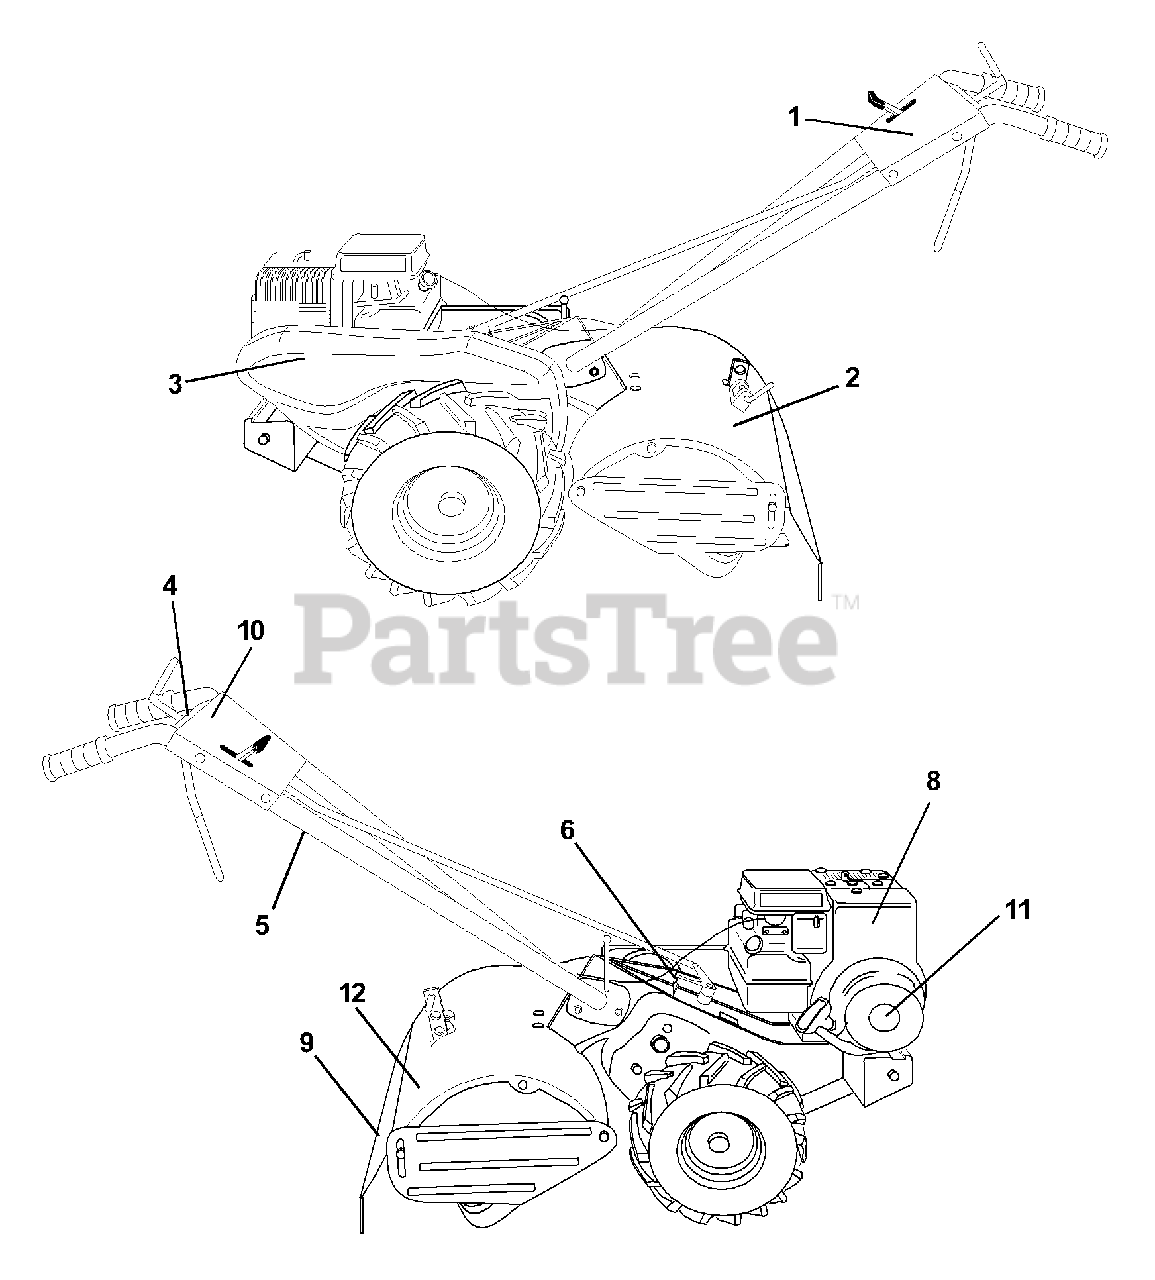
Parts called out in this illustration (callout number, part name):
1	Decal, Logo
2	Decal, Description
3	Decal, Logo
4	Decal, Instruction, Tilling
5	Decal, Hand Placement
6	Decal, Shift Indicator
8	Decal, Briggs & Stratton
9	Decal, Warning, Rotating Tines
10	Decal, Reverse
12	Decal, Tine Shield Wrng Dom
